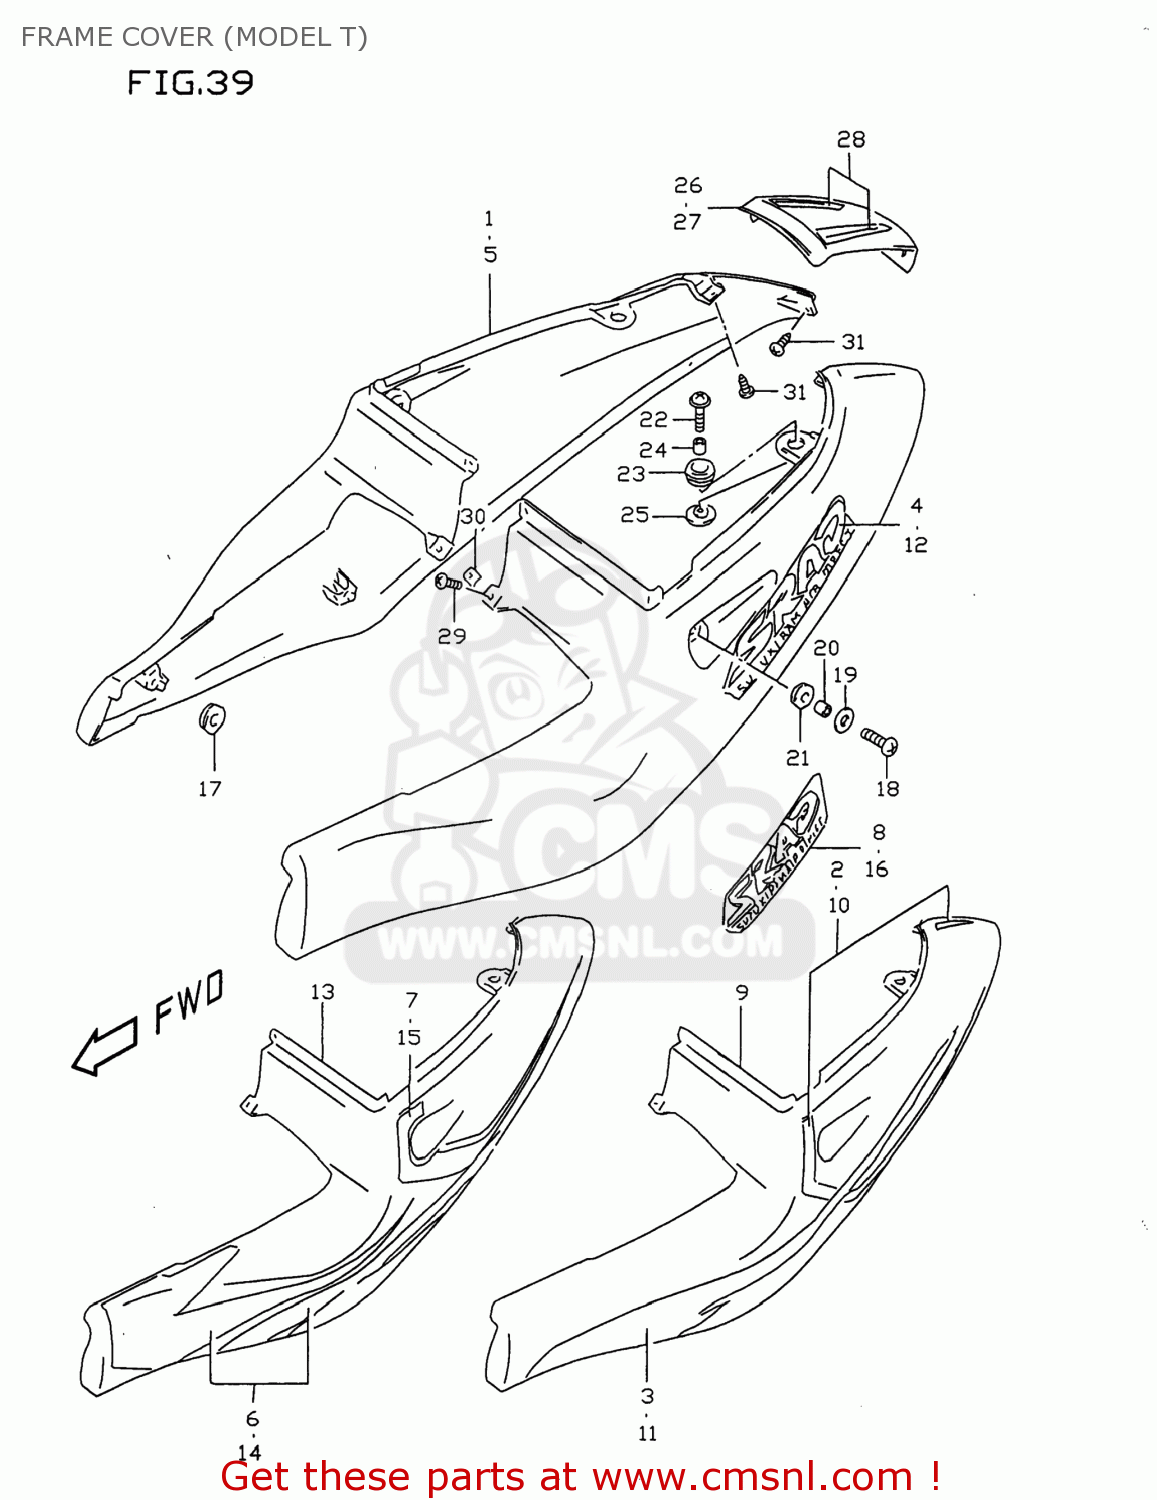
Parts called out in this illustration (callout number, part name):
1	COVER,FRAME,R(BROWN)
2	TAPE SET,FRAME COVER,R(YELLOW)
3	TAPE,FRAME COVER,RIGHT
4	EMBLEM,FRAME COVER
5	COVER,FRAME,R(WHITE)
6	TAPE SET,FRAME COVER,RIGHT
7	TAPE,FRAME COVER,R
8	EMBLEM,FRAME COVER
9	COVER,FRAME,L(BROWN)
10	TAPE SET,FRAME COVER,L(YELLOW)
11	TAPE,FRAME COVER,L
12	EMBLEM,FRAME COVER
13	COVER,FRAME,L(WHITE)
14	TAPE SET,FRAME COVER,LEFT
15	TAPE,FRAME COVER,LEFT
16	EMBLEM,FRAME COVER
17	CUSHION
18	SCREW(6X20)
19	WASHER(6.5X22X1.6)
20	SPACER (6.3X9.1X6.7)
21	CUSHION
22	SCREW(6X25)
23	CUSHION,TAIL COVER UPR
24	SPACER (6,8X10X9.4)
25	CUSHION,FRAME COVER LWR
26	COVER,FRAME CTR
27	COVER,FRAME CTR
28	TAPE SET,FRAME COVER C
29	SCREW
30	NUT
31	SCREW
